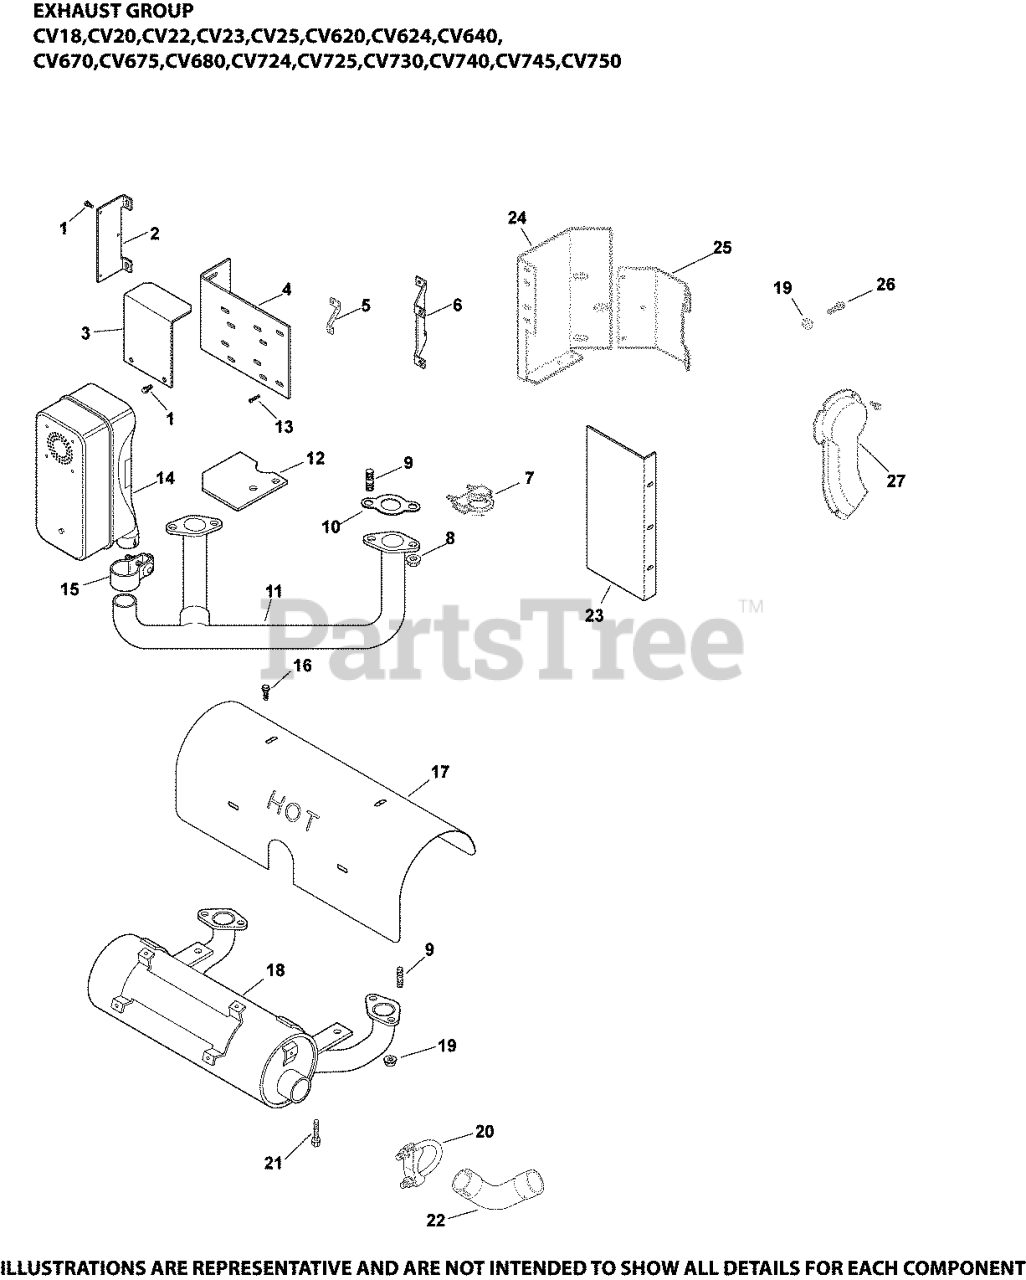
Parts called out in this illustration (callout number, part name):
1	SCREW,FLG THD FRM M6X1.0X16-(#25086397S)
8	NUT, FLG M8X1.25
9	STUD, EXHAUST-USE 25 072 24-S
21	SCREW,FLG THD FRM M6X1.0X20-(#25086396S)
